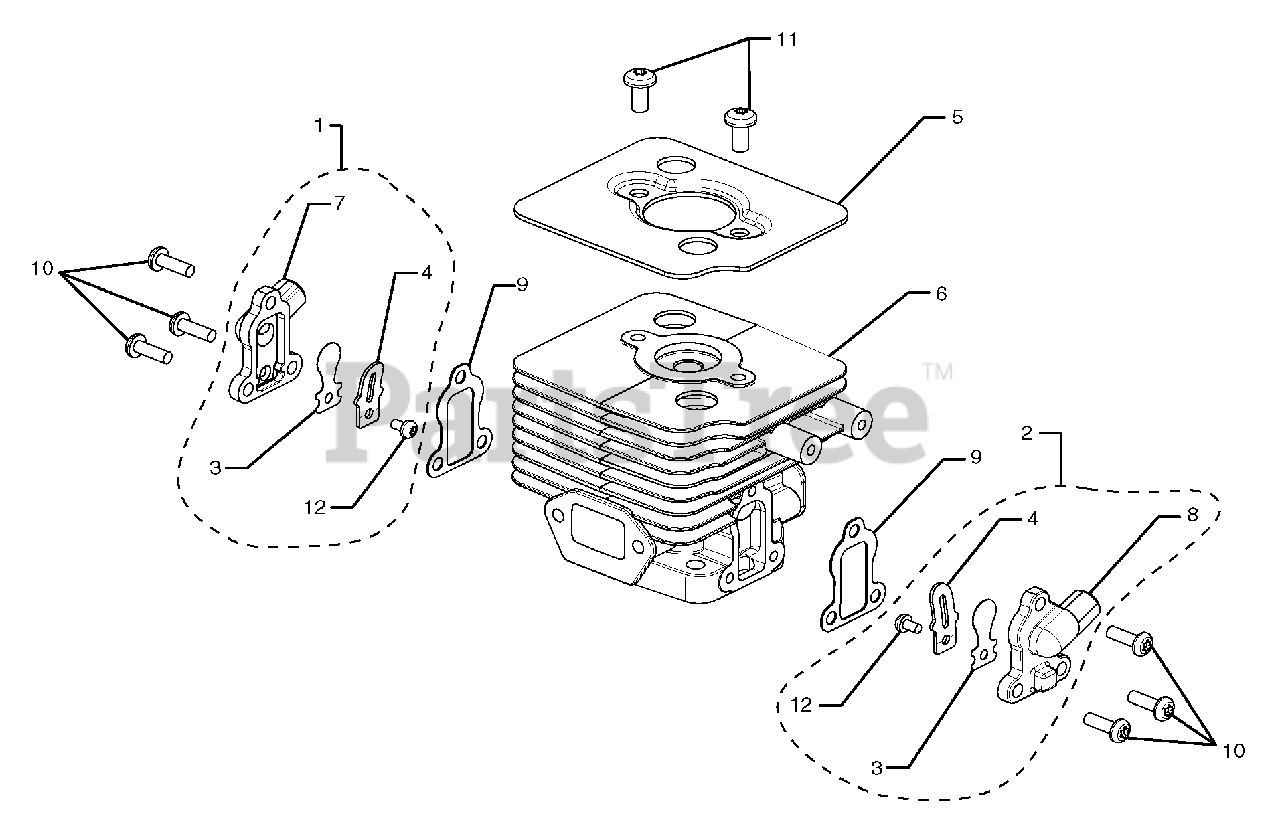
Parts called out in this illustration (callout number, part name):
1	Start Side Reed Valve Assembly
2	Flywheel Side Reed Valve Assembly
3	Stamping Petal Reed Valve
4	Stamping Stop Reed Valve
5	Cylinder Plate
6	Stratified Cylinder
7	Starter Side Cover Valve
8	Flywheel Side Cover Valve
9	Reed Valve Cover Gasket
10	Screw (M4 x 0.7 x 12 in. Torx Recessed Pan Head, Machine)
11	Screw (M5 x 0.8 x 10 in. Torx Recessed Pan Head, Machine)
12	Screw (M3 x 0.5 x 5 in. Torx Recessed Pan Head, Machine)
